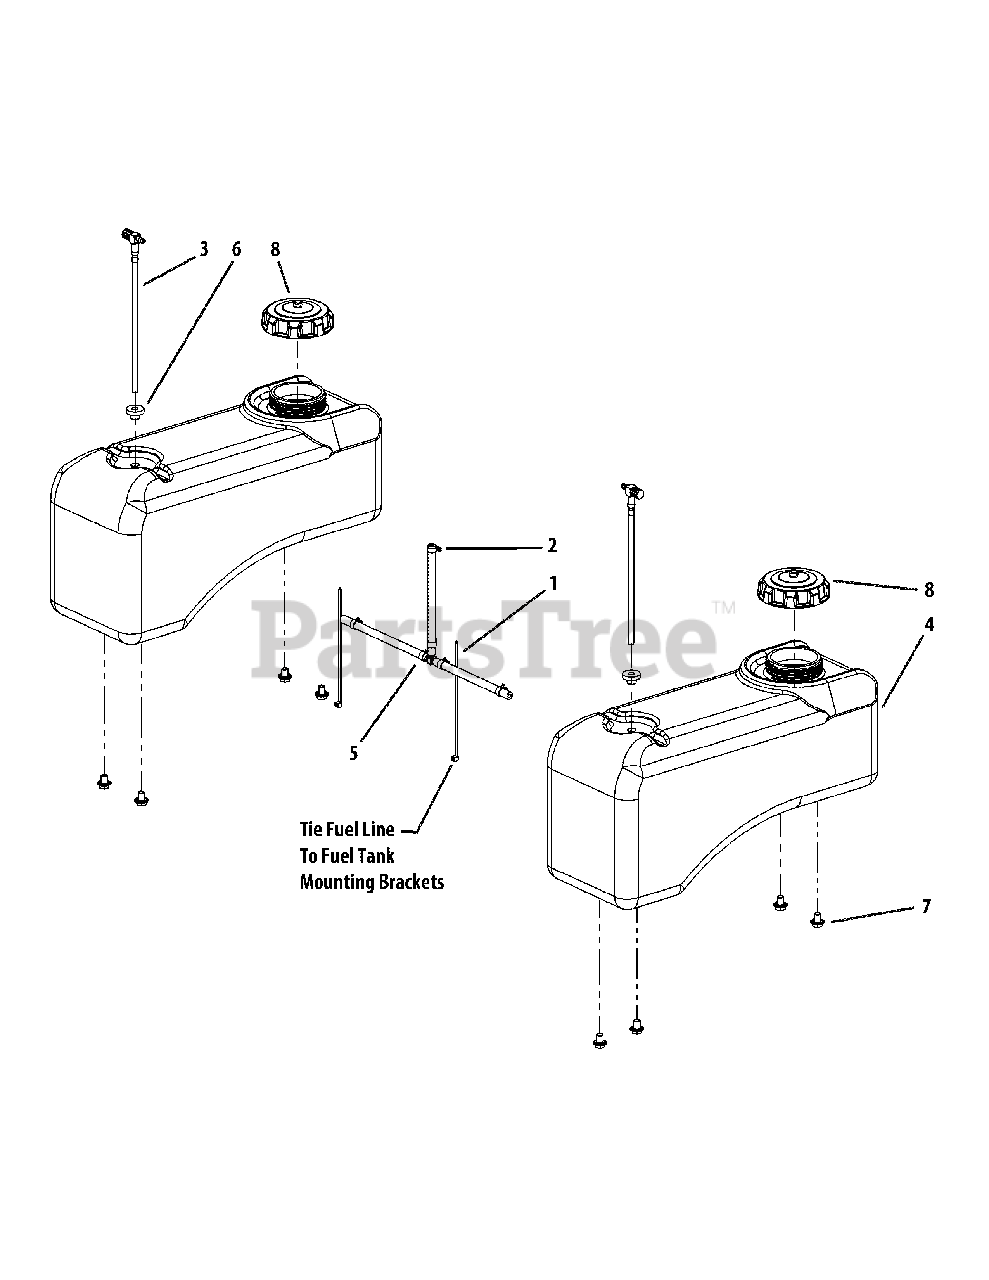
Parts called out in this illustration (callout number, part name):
1	Cable Tie
2	Hose Clamp, SAE #4: 1/4-5/8, SS
3	Fuel Fitting
4	Fuel Tank
5	Fuel Hose Assembly includes:
5	Hose, 1/4" Fuel Line (in inches)
5	Clamp, Union
5	Tee Fitting, Fuel
6	Grommet, Fuel Tank
7	Hex Cap Screw, 3/8-16 x .500
8	Fuel Cap, 3.5, Tethered
